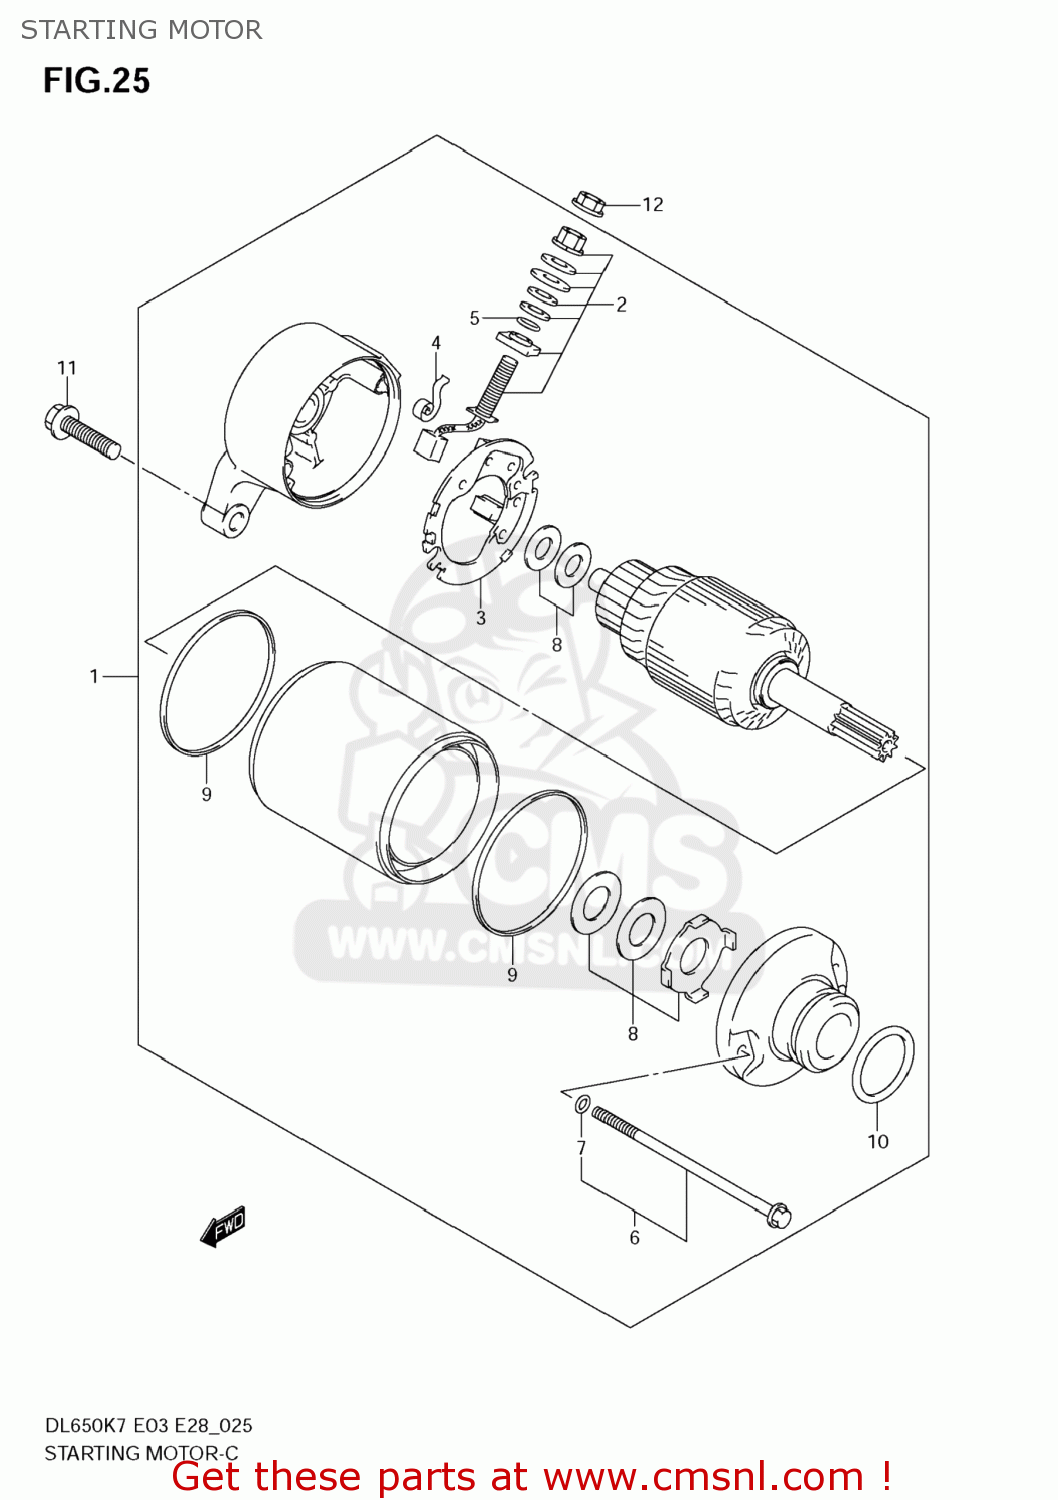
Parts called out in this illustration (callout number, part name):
1	MOTOR ASSEMBLY,STARTING
2	BRUSH TERMINAL SET
3	BRUSH HOLDER SET
4	SPRING,BRUSH
5	O RING
6	BOLT SET
7	O RING
8	SHIM SET,STARTING MOTOR
9	O RING
10	O RING(D:3,ID:24.5)
11	BOLT(6X25)
12	NUT
